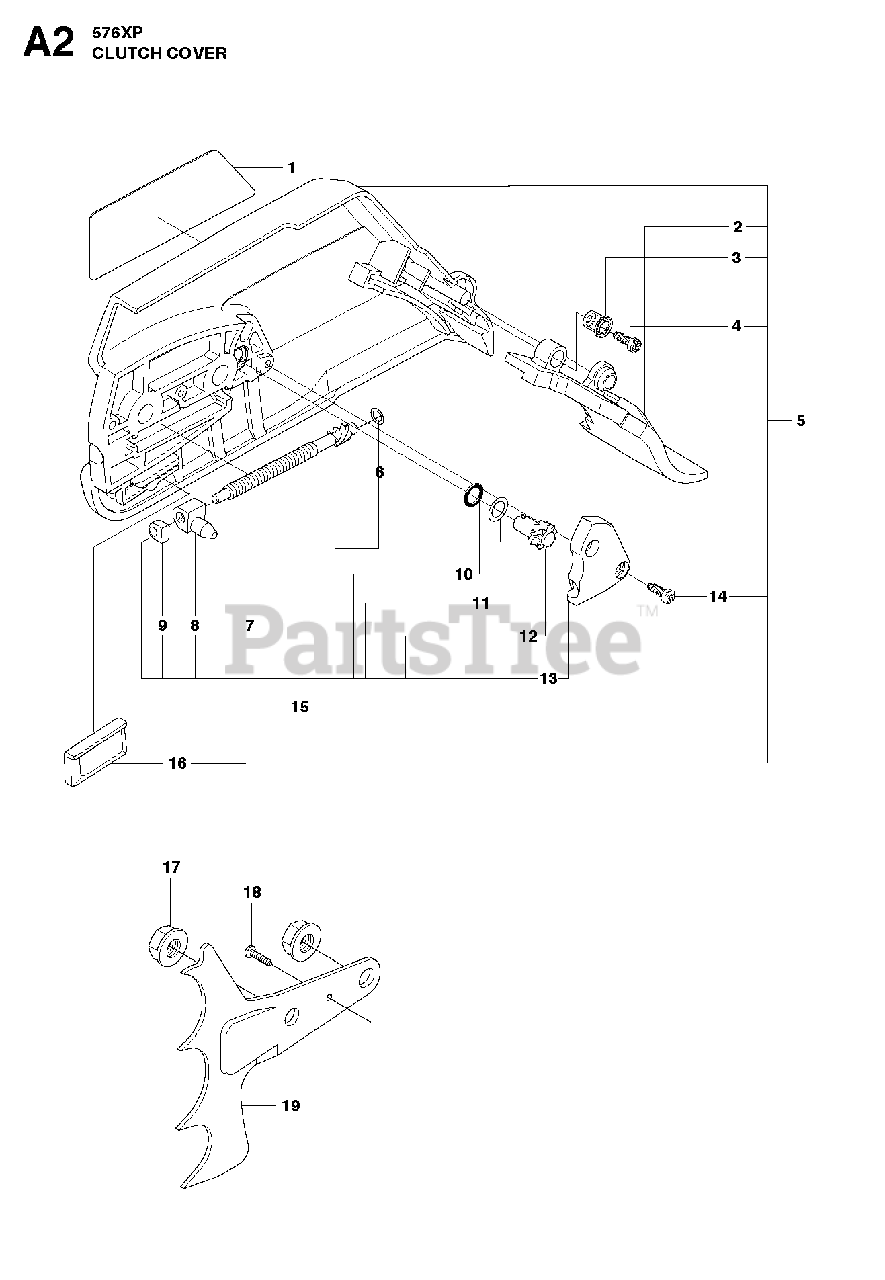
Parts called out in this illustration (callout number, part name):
2	PROTECTOR
3	WASHER
4	SCREW
5	CLUTCH COVER ASSY
6	WASHER
7	ADJUSTER
8	PAWL
9	SLEEVE
10	O-RING
11	WASHER
12	RP ADJUSTER
13	COVER
14	SCREW
15	KIT-CHAIN TENSIONER
16	CHAIN GUIDE
17	NUT M8 FLANGE
19	SPIKE OUTER
